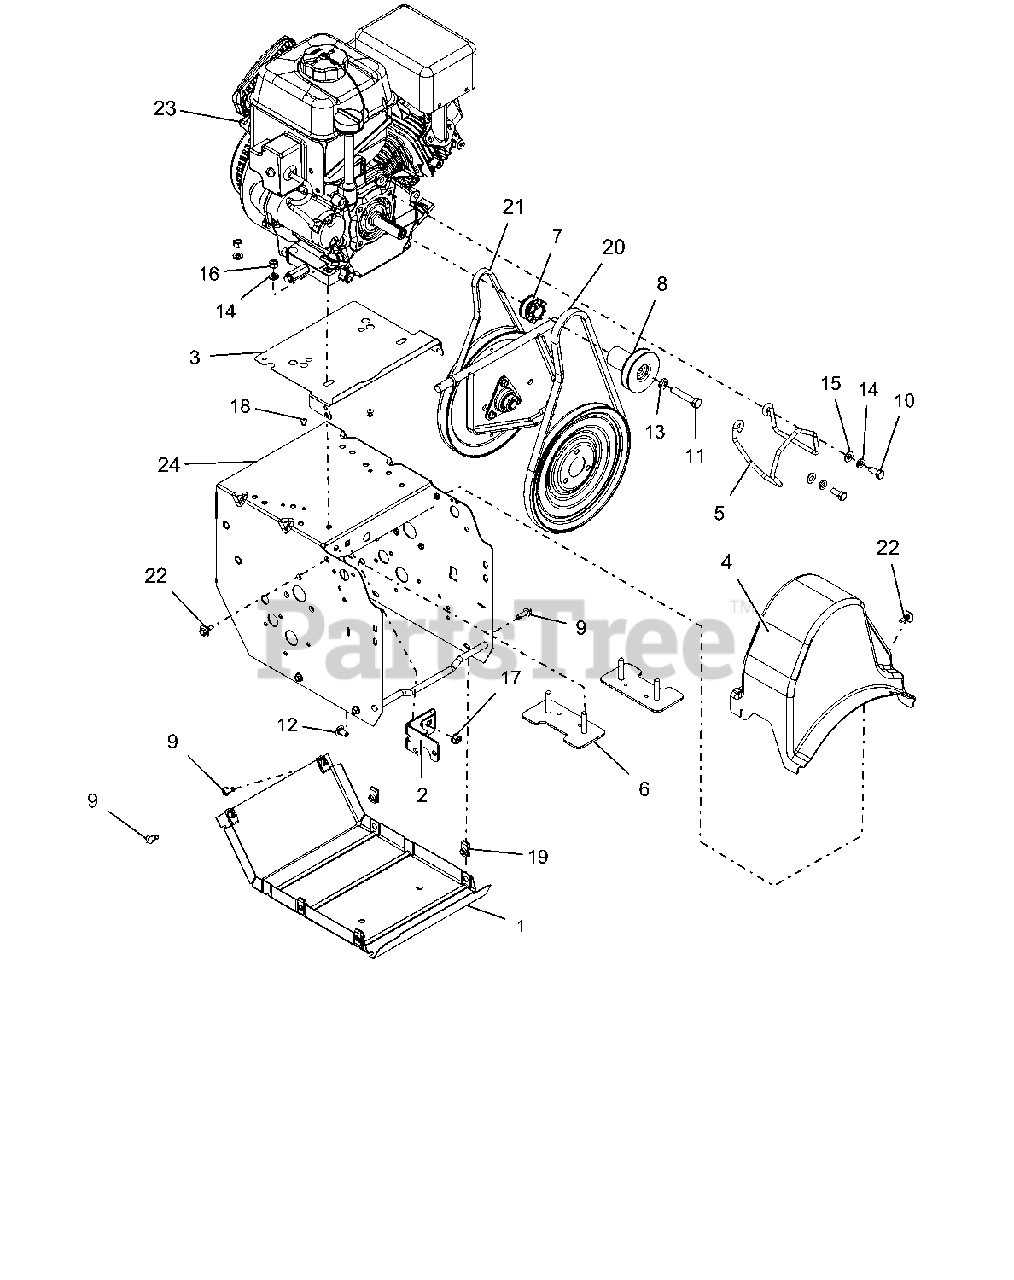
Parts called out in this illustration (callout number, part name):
1	COVER, BOTTOM
2	WELDMENT, FRAME BRACKET
3	BAFFLE, COMPACT
4	COVER, COMPACT BELT
5	FINGER, BELT
6	STRAP, ENGINE BOLT-WELDMENT
7	SHEAVE, TRACTION
8	SHEAVE,AUGER 3/4" PM
9	BLT-HEX .25-20X.75 HWH YZ GR5
10	BLT-HEX .31-24X.75 YWZC GR5
11	BLT-HEX .38-24X2.0 YWZC
12	@BLT-RHDSSQNK .31-18X.62 G5YZ
13	WSHR-LK .375X.115 HVY YWZC
14	WSHR-LK .312X.097 HVY YWZC
15	@WSHR-FL-STL.344X.688X.065YWZC
16	@NUT-HEX .31-18 YWZC
17	@NUT-LK-TOP-FLG .31-18 YWZC
18	RVT-POP .187 YZ
19	NUT-RTNR .25-20X.56
20	V-BELT, HA-RAW EDGE
21	V-BELT, 3L-WRAPPED
22	SCR-TAP .25-20X.5 CAPTIVE
23	ENGINE, SNO-TEK 208 120V
24	FRAME, MAIN
